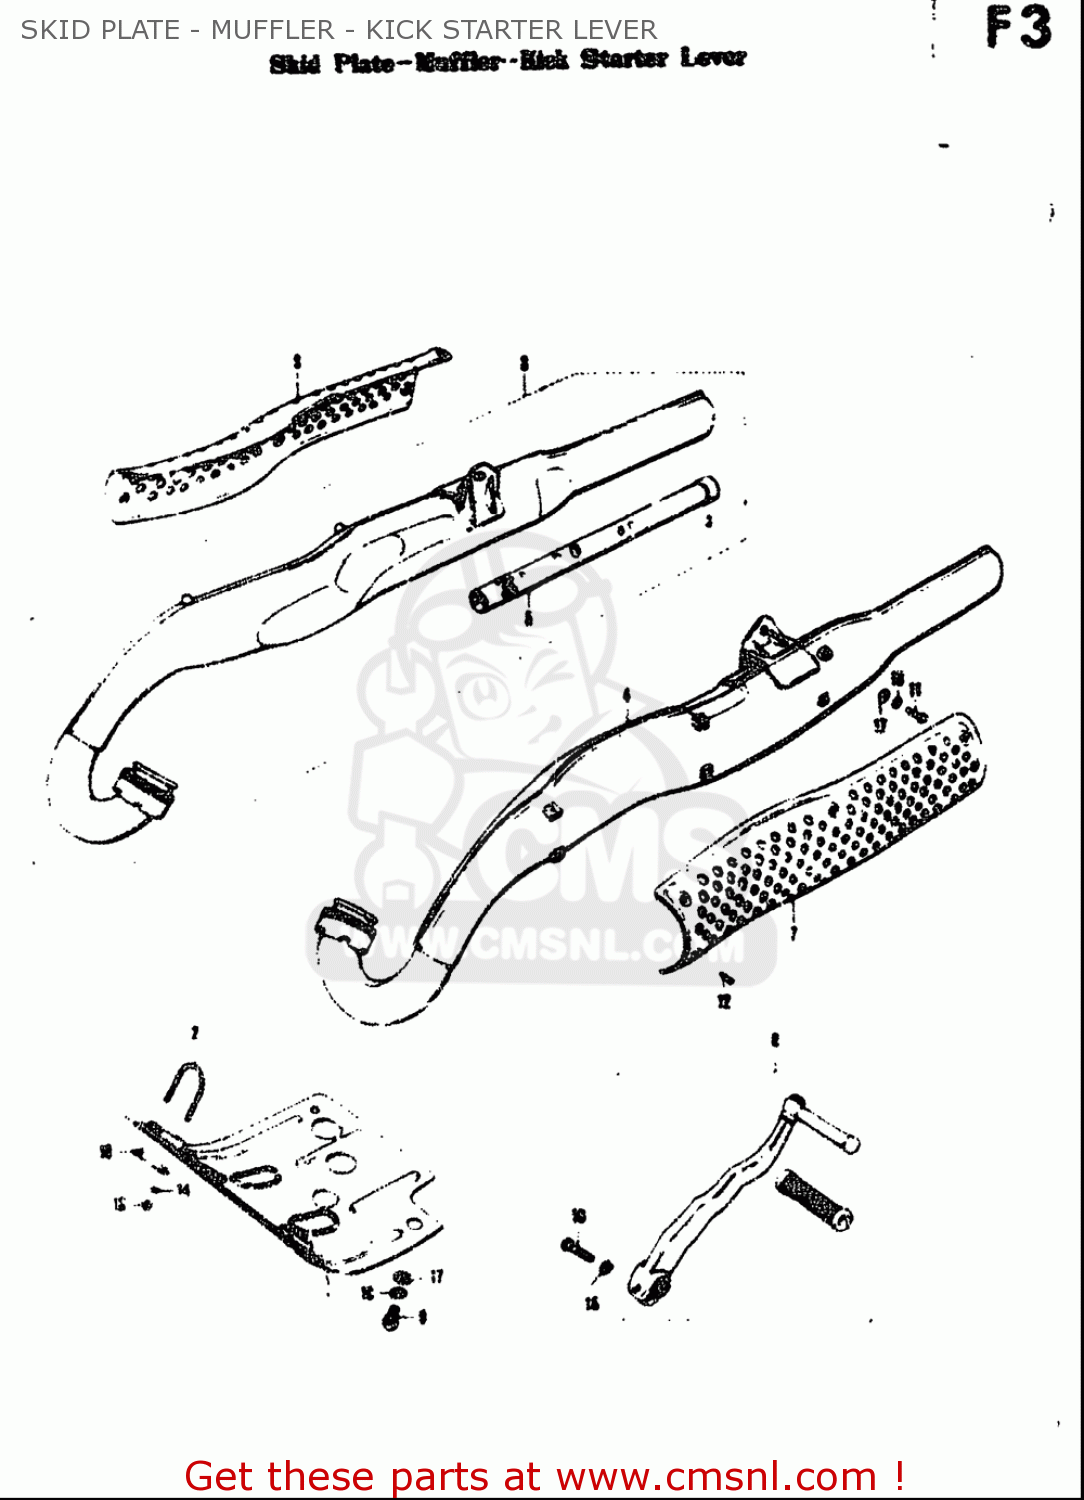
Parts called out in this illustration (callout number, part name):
9	BOLT
10	BOLT
11	BOLT
13	NUT
14	WASHER,LOCK
15	WASHER,LOCK
16	WASHER,LOCK
17	WASHER
18	WASHER
